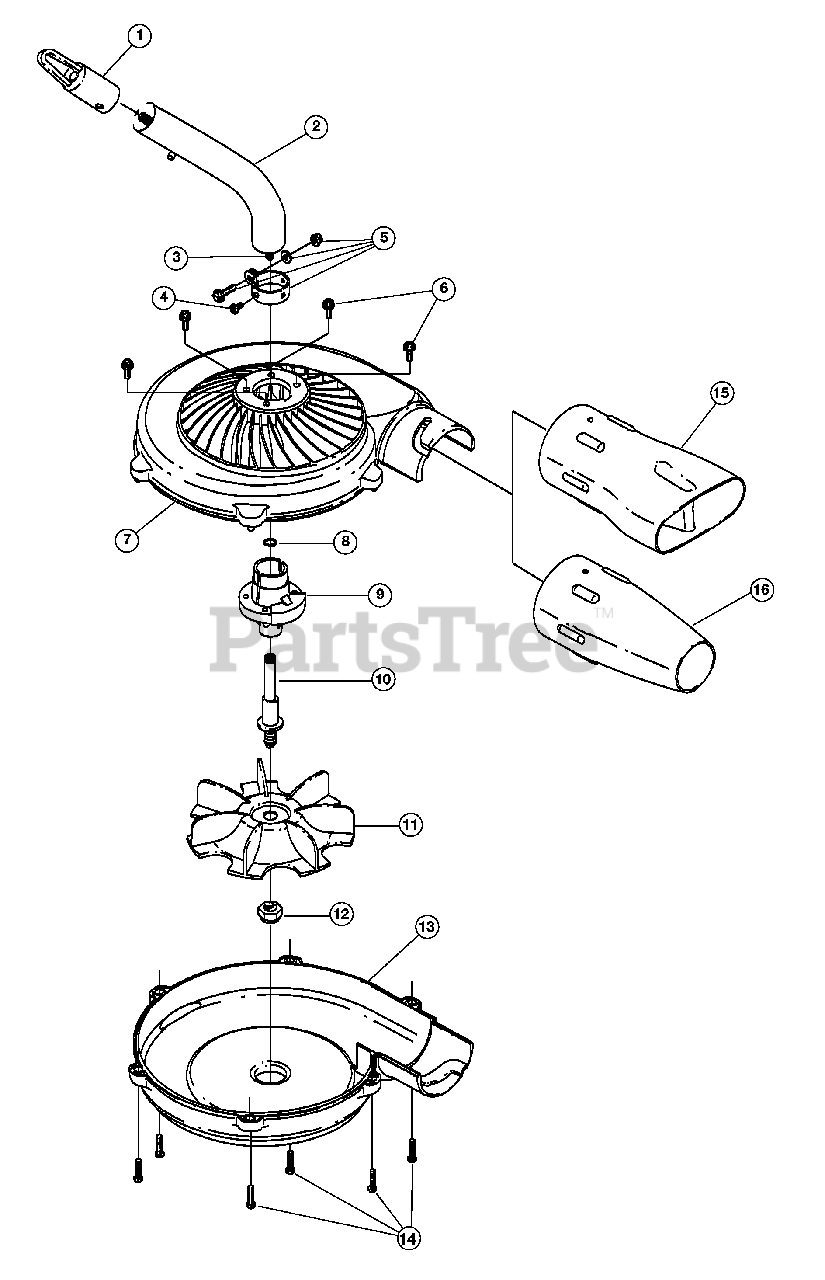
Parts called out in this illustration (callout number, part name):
1	Hanger
2	Drive Shaft Housing Assembly
3	Drive Shaft Assembly
4	Anti-Rotation Screw
5	Lower Clamp Assembly
6	Mounting Screw
7	Upper Housing
8	Palnut
9	Bushing Assembly Housing
10	Shaft Impeller
11	Impeller
12	Lock Nut
13	Lower Housing
14	Mounting Screw
15	Flare Nozzle
16	Concentrator Nozzle
